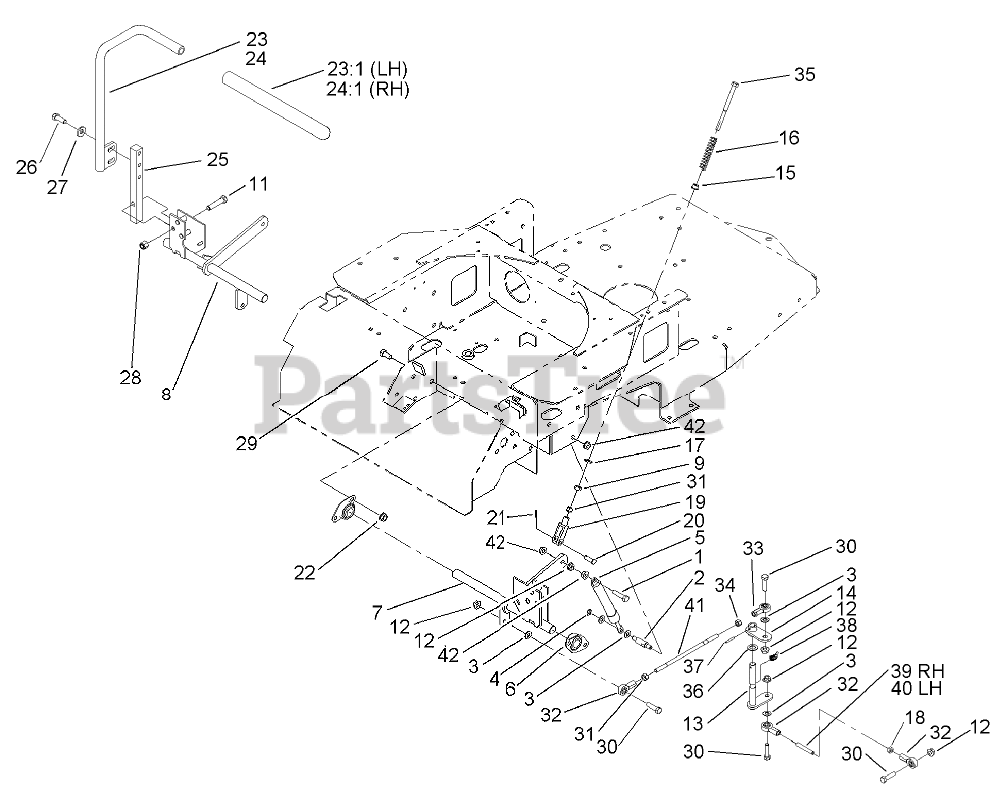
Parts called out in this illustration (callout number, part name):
1	SCREW-HH
2	PIN-DAMPER
3	WASHER-PLAIN
4	RING-RETAINING, EXT
5	Damper-Control, Motion
6	BEARING-FLANGE, SIDE
7	BRACKET-MOTION CONTROL, LH
8	BRACKET-MOTION CONTROL, RH
9	NUT-LOCK
11	SCREW-HH
12	NUT-HF
13	PIVOT ASM
14	PIVOT PLATE ASM
15	BUSHING-FLANGED
16	SPRING-RETURN, NEUTRAL
17	WASHER-FLAT
18	NUT-JAM
19	YOKE-ADJUSTABLE
20	PIN-CLEVIS
21	PIN-COTTER
22	NUT-HHF, WHIZ
23	LH LEVER ASM
23:1	GRIP-CONTROL, MOTION
24	RH LEVER ASM
24:1	GRIP-CONTROL, MOTION
25	ARM-SHAFT, CONTROL
26	SCREW-HH
27	WASHER-BELLEVILLE
28	NUT-LOCK, NI
29	SCREW-HH
30	SCREW-HH
31	NUT-HEX
32	BALLJOINT-RH
33	BALLJOINT-LH
35	BOLT-RETURN, NEUTRAL
36	WASHER
37	PIN-ROLL
38	FITTING-LUBE, 45 DEG
39	LINKAGE-LOWER, RH
40	LINKAGE-LOWER, LH
41	LINKAGE-UPPER
42	NUT-HF
